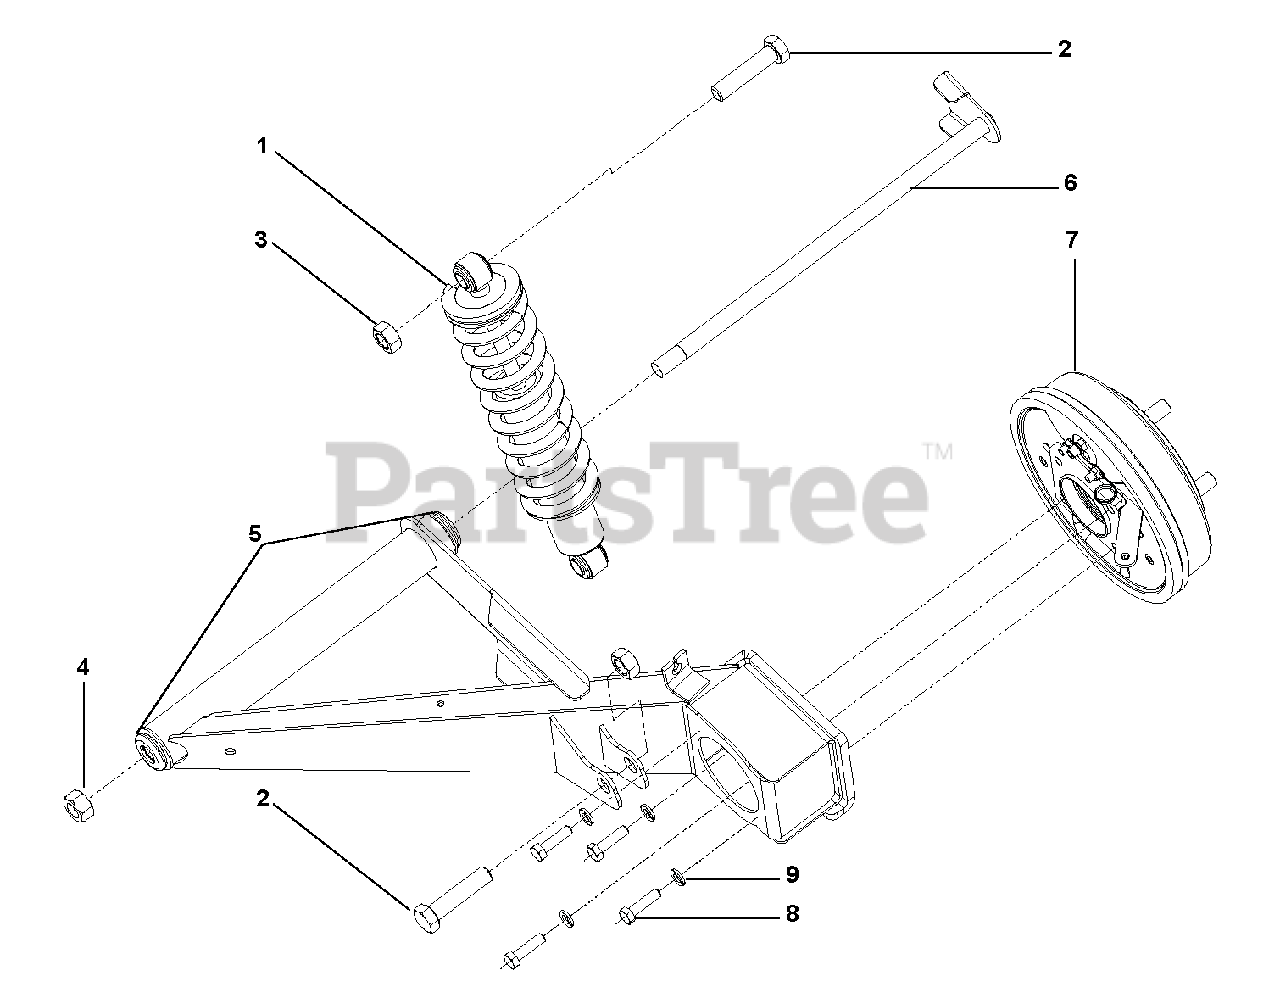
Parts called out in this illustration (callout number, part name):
1	SHOCK COIL REAR TRUCK
2	HHCS M14X2.00X60 GR8.8
3	NUT HEX NYLOCK M14X2.00
4	NUT-LK-TOP .563-12 GR5 YWZC
5	BUSHING IDLER ARM RUBBER
6	CENTER PIVOT TUBE WELDMENT
7	RH DRUM ASM 180MM 4 ON 4" BC
8	HHCS M8X1.25X30 GR10.9 YLW PLT
9	WSHR-LK M8 YWZC
